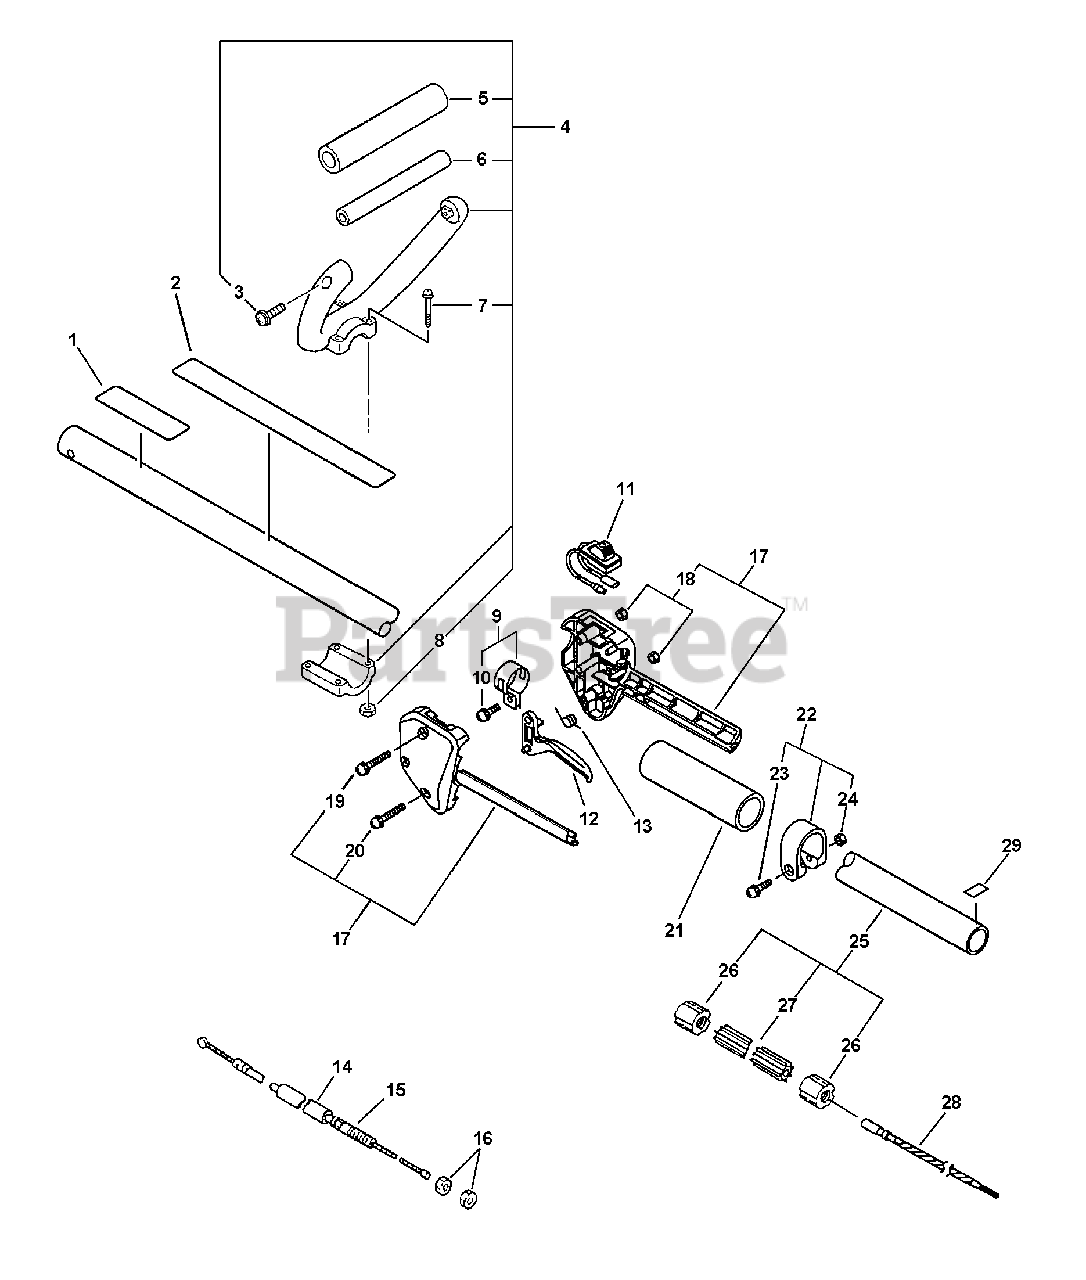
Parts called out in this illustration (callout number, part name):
1	Label, Caution
2	Label, Caution
3	Screw 5x30
4	Loop Handle Asy
5	Grip, Front Handle
6	Handle, Front
7	Screw 5x35
9	Band
10	Screw 5x14
11	Switch, Ignition
12	Contorl, Throttle
13	Spring, Throttle Return
15	Cable, Throttle
17	Throttle Bracket Set
19	Screw 5x35
20	Screw 5x25
21	Grip, Front Handle
22	Band 25
23	Screw 5x30
25	Driveshaft Housing Asy
26	Fixture, Liner
27	Liner, Flexible
28	Shaft, Flexible
29	Label, Location
